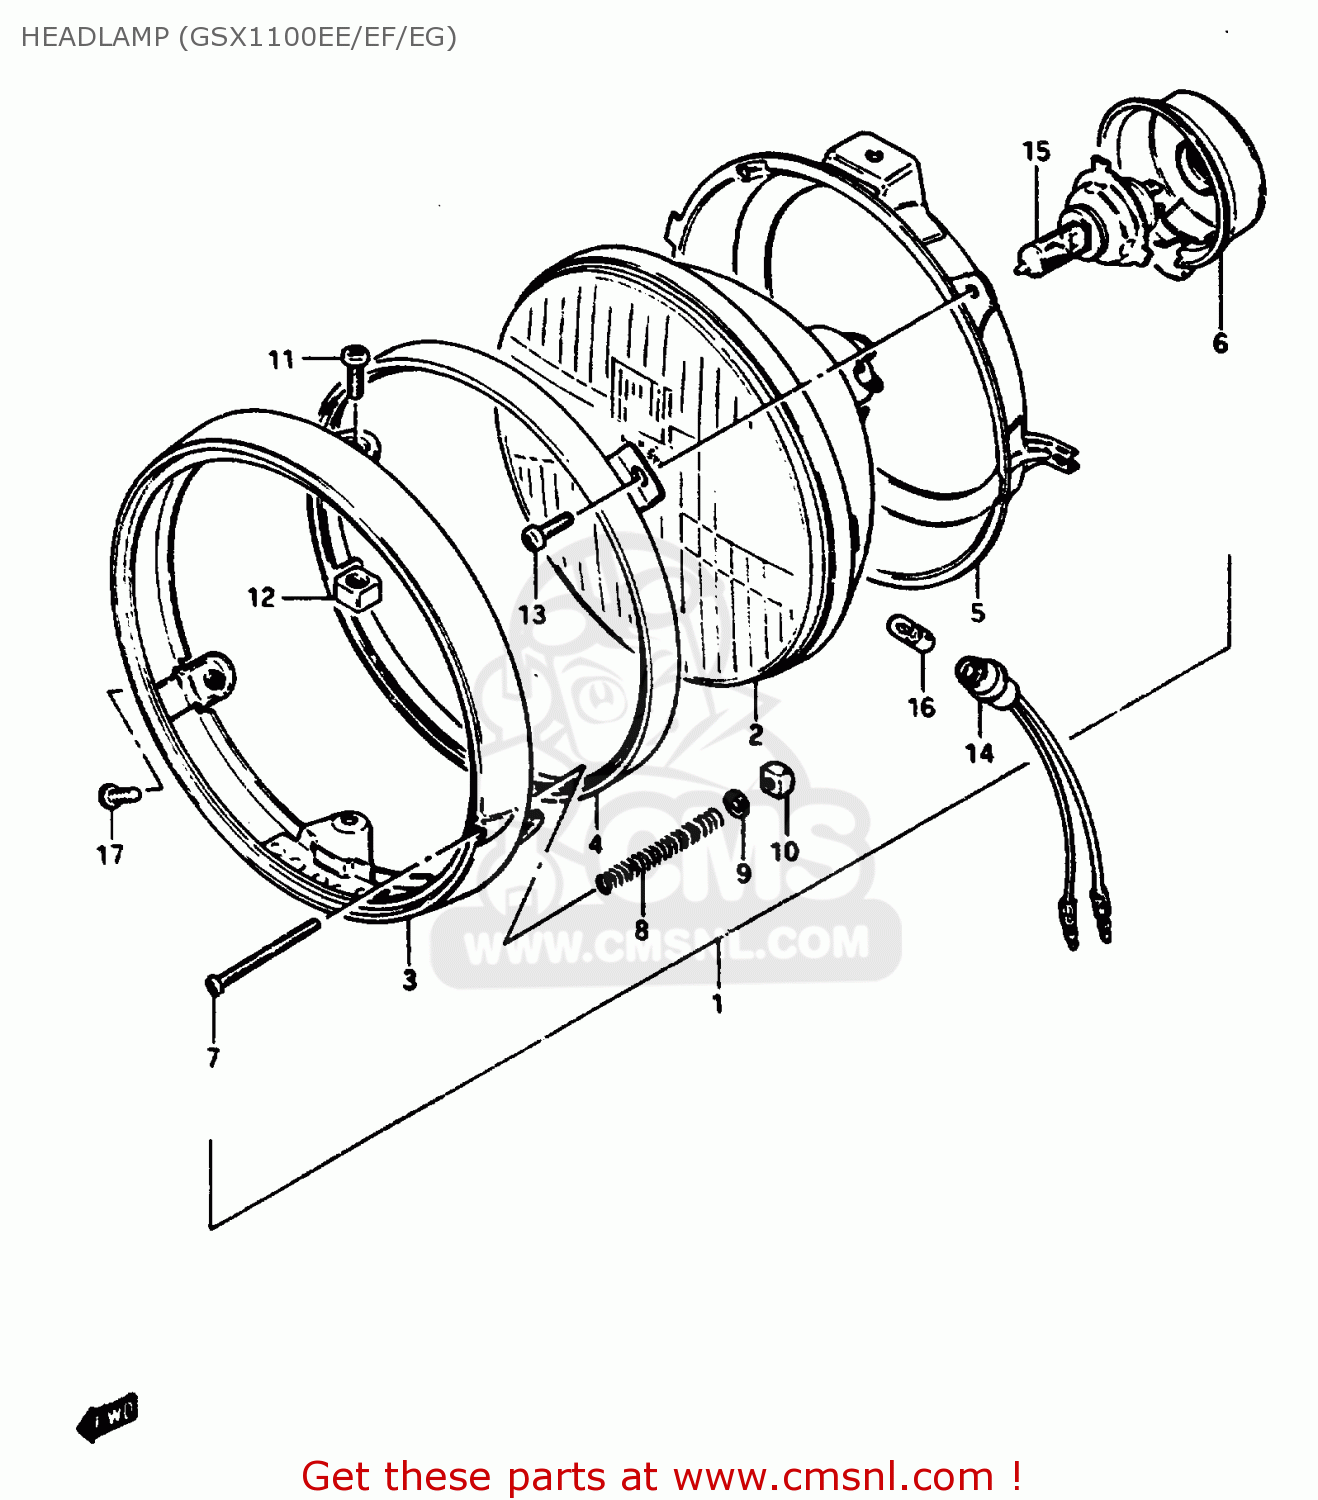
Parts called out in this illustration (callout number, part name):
1	HEADLAMP ASSY
2	LAMP UNIT
3	RIM,HEADLAMP
4	RETAINER
5	RING,MOUNTING
6	COVER,HEADLAMP SOCKET
7	SCREW
8	SPRING,HEADLAMP ADJUST
9	WASHER
10	NUT
11	SCREW
12	NUT
13	SCREW
14	SOCKET,PARKING
15	BULB(12V60/55W,H4)
16	BULB(12V4W)
17	SCREW
